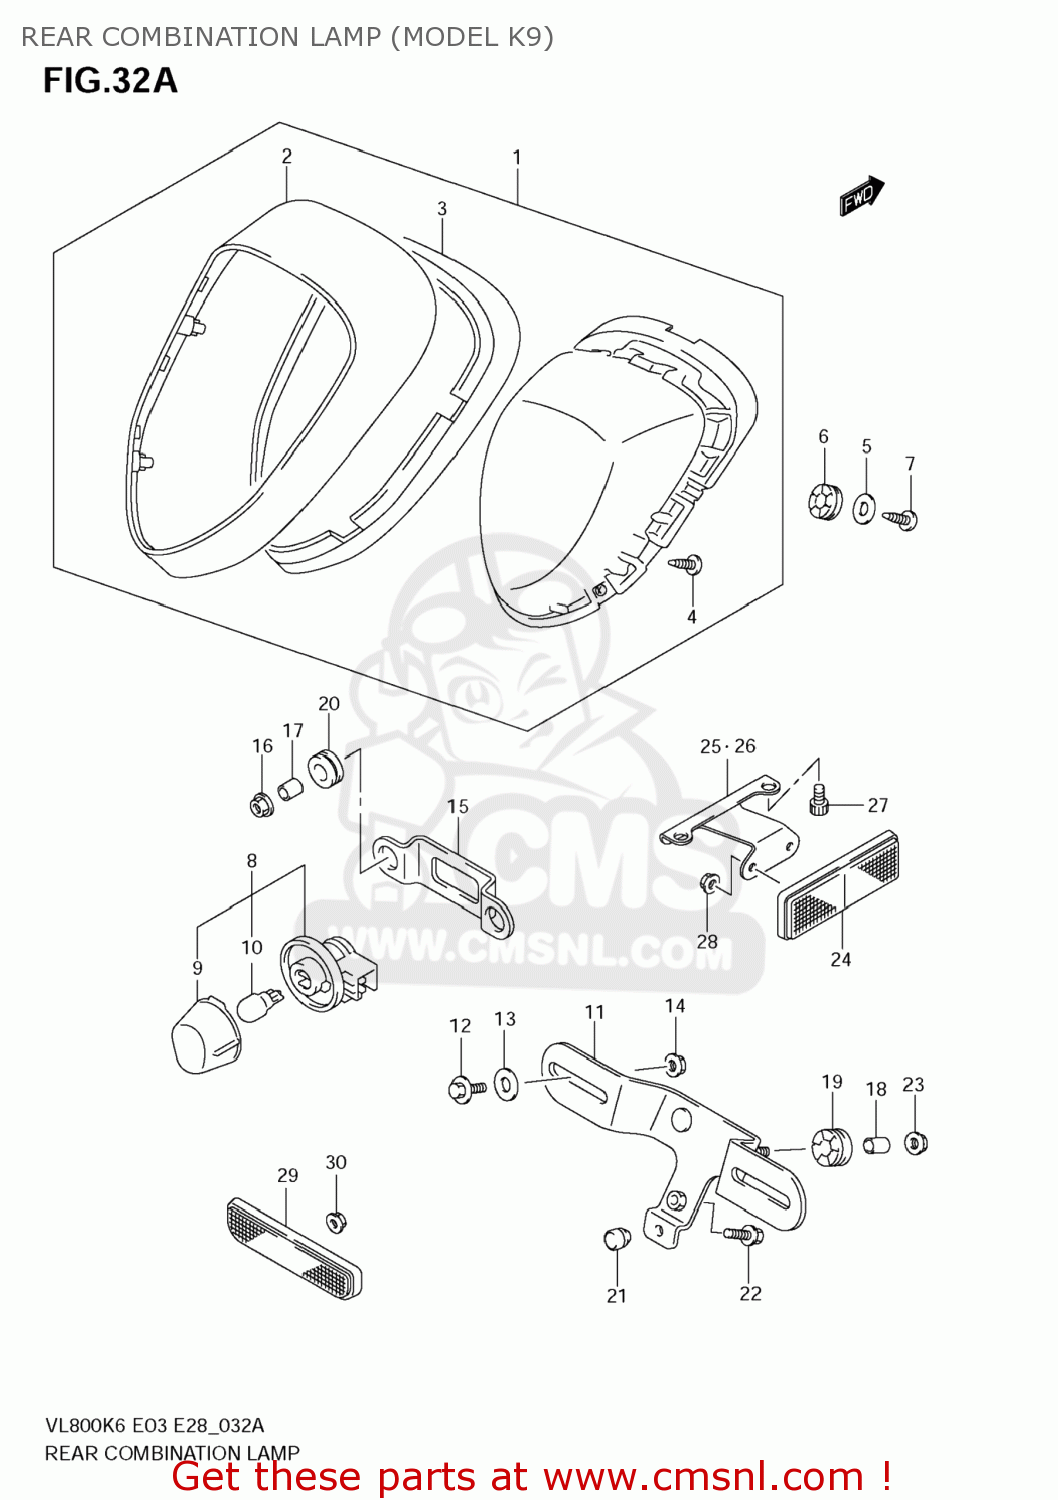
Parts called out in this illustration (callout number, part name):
1	LAMP ASSY,RR COMBINATION
2	COVER
3	RUBBER
4	SCREW(3X12)
5	WASHER(5.5X20X1.2)
6	CUSHION,RR COMBINATION
7	SCREW
8	LAMP ASSY,LICENSE
9	LENS
10	BULB(12V5W)
11	BRACKET,LICENSE PLATE
12	BOLT(6X16)
13	WASHER(6.5X20X1.2)
14	NUT
15	BRACKET,LICENSE LAMP
16	NUT
17	SPACER(5.5X9.5X10)
18	SPACER(6.5X10X12)
19	CUSHION
20	CUSHION
21	CUSHION
22	BOLT
23	NUT
24	REFLECTOR ASSY,RR
25	BRACKET,RR SIDE RR,R
26	BRACKET,RR SIDE RR,L
27	BOLT
28	NUT
29	REFLECTOR ASSY,RR
30	NUT
